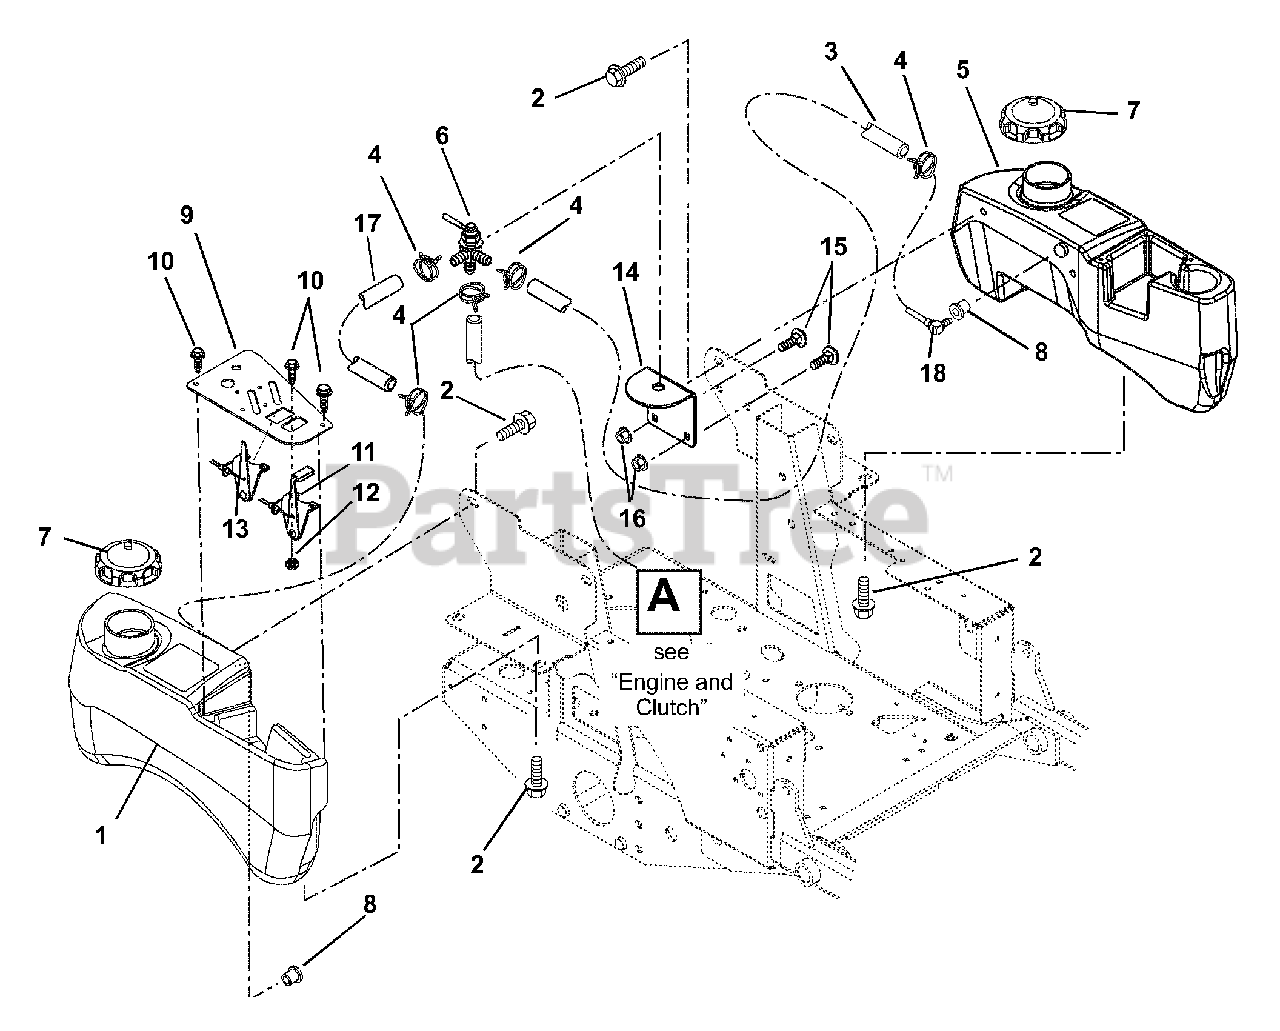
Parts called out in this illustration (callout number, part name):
1	Tank, Gas- Right Hand
2	Bolt, SEMS .31-18 x .62
3	Hose, Gas Line 5.50"-.25" I.D.
4	Hose, Clamp
5	Tank, Left Hand Fuel (Eye-Q)
6	Valve, Fuel
7	Cap, Fuel
9	Panel, Control
10	Screw, Machine 10-24 x .50 Hex Washer Head
11	Cable, Throttle
12	Nut, Locking Nylon 10-24 With Insert
13	Cable, Choke
14	Bracket, Fuel Valve Mounting
15	Bolt, Round Head Square Neck .31-18 x .75 Grade 5
16	Nut, Nyloc Flange 5/16-18
17	Hose, Gas Line 29"-.25" I.D.
18	Fitting, Tank Elbow .31 Hose
